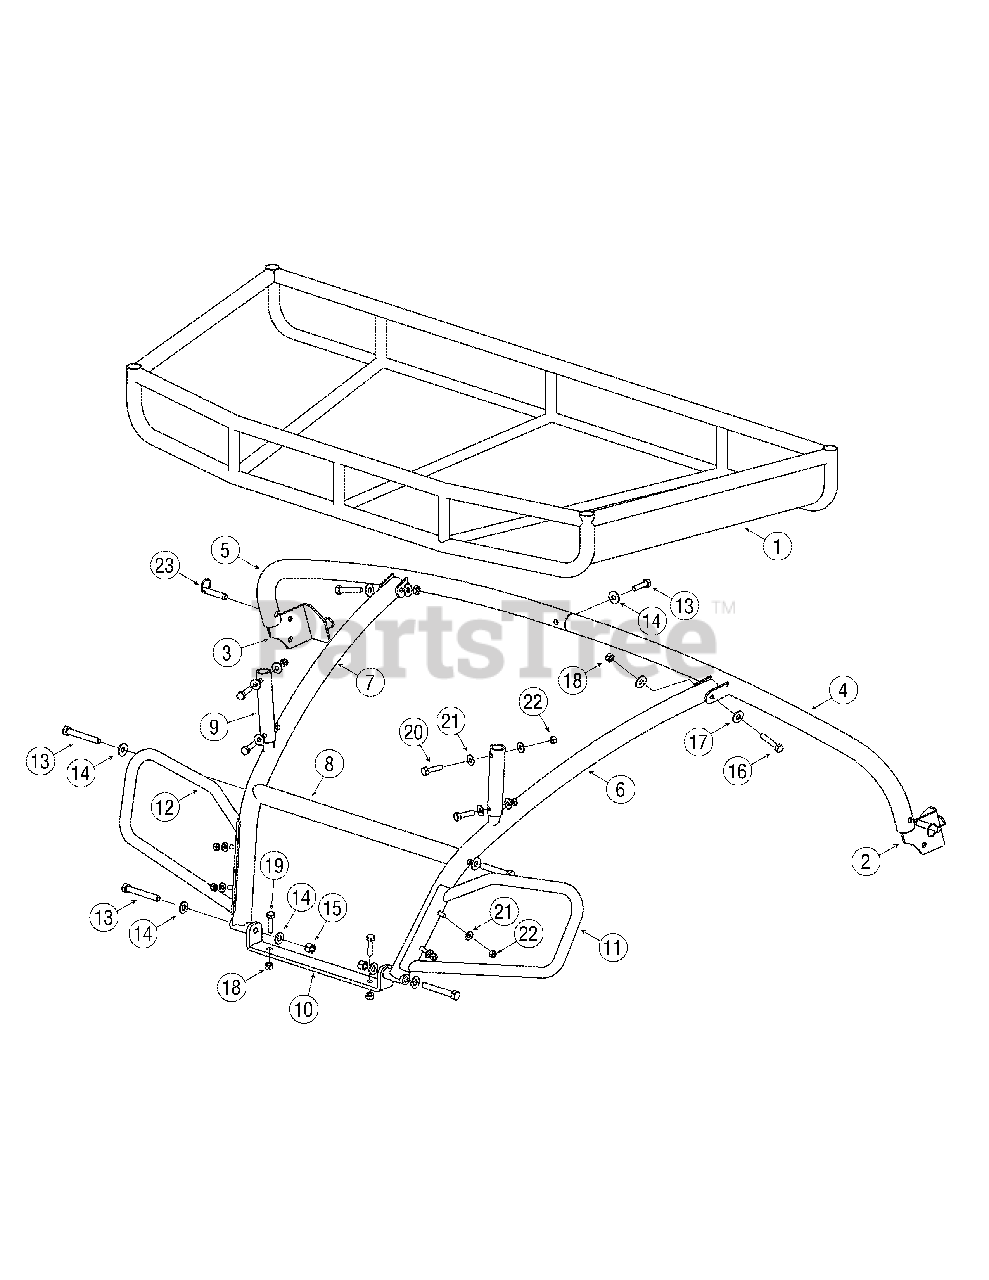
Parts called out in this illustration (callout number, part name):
2	Frame Mount - LH
3	Frame Mount - RH
4	Transverse Rack Support, Driv
5	Transverse Rack Support, Pass
6	Long, Rack Support, Driver
7	Long, Rack Support, Pass
8	Center Brace
9	Rack Support, Vert
10	Bumper Hinge Plate
11	Light Guard, Driver
12	Light Guard, Pass
13	Hhcs, 3/8-16 x 2.75
14	Wash, Flat, .406 x .812 x .051
15	Nut, Hexlk, 3/8-16
16	Hhcs, 5/16-18 x 2.00
17	Wash, Flat, .344 x .688 x .065
18	Nut, Hexlk, 5/16-18
19	Hhcs, 5/16-18 x 1.00
20	Hhcs, 1/4-20 x 1.50
21	Wash, Flat, .271 x .630 x .065
22	Nut, Hexlk, 1/4-20
23	Ball Lock Pin, 3/8" x 2.00
